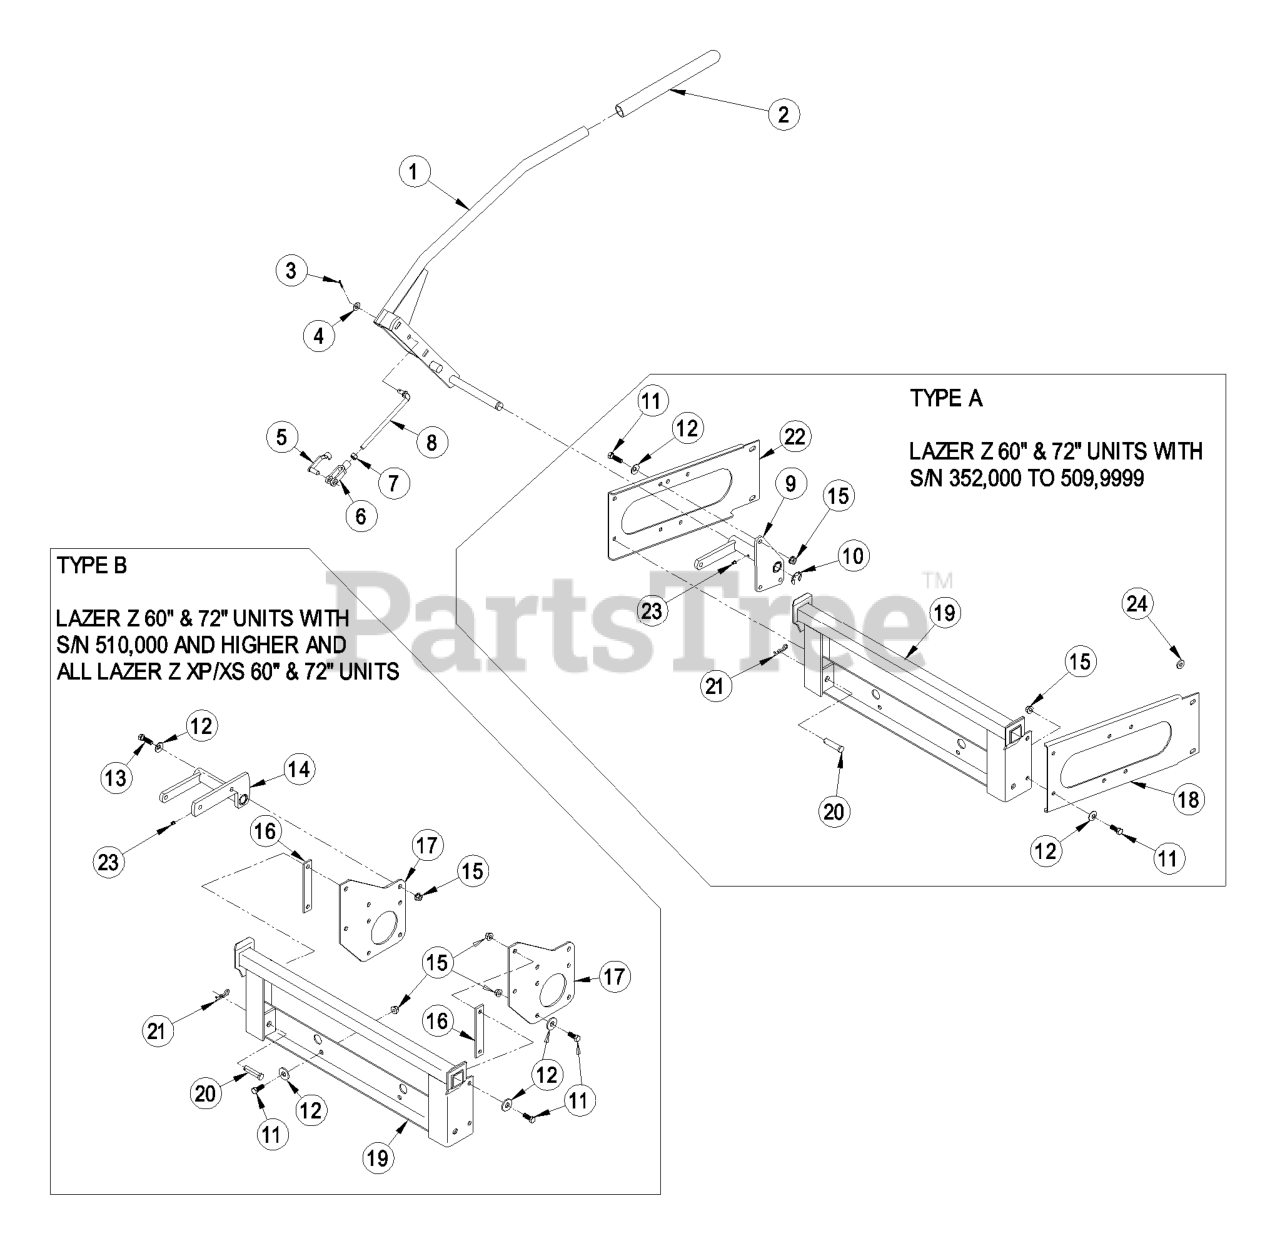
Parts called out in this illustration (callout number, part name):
1	HANDLE AND GRIP ASM
2	GRIP-HANDLE
3	PIN-COTTER
4	WASHER-FLAT
5	PIN-SPRING, CLEVIS
6	YOKE-LINKAGE, BRAKE
7	NUT-HEX
8	LINK-HANDLE
9	WLD, HANDLE MOUNT
11	SCREW-HH
12	WASHER-BELLEVILLE
13	SCREW-HH
14	WLD, HANDLE MOUNT - XP
15	NUT-HHF, WHIZ
17	PLATE-MOUNT, BAGGER
18	BRACKET-FRAME, RH
19	MOUNT-BAGGER
20	PIN-CLEVIS
21	PIN-COTTER
22	BRACKET-FRAME, LH
23	FITTING-GREASE
